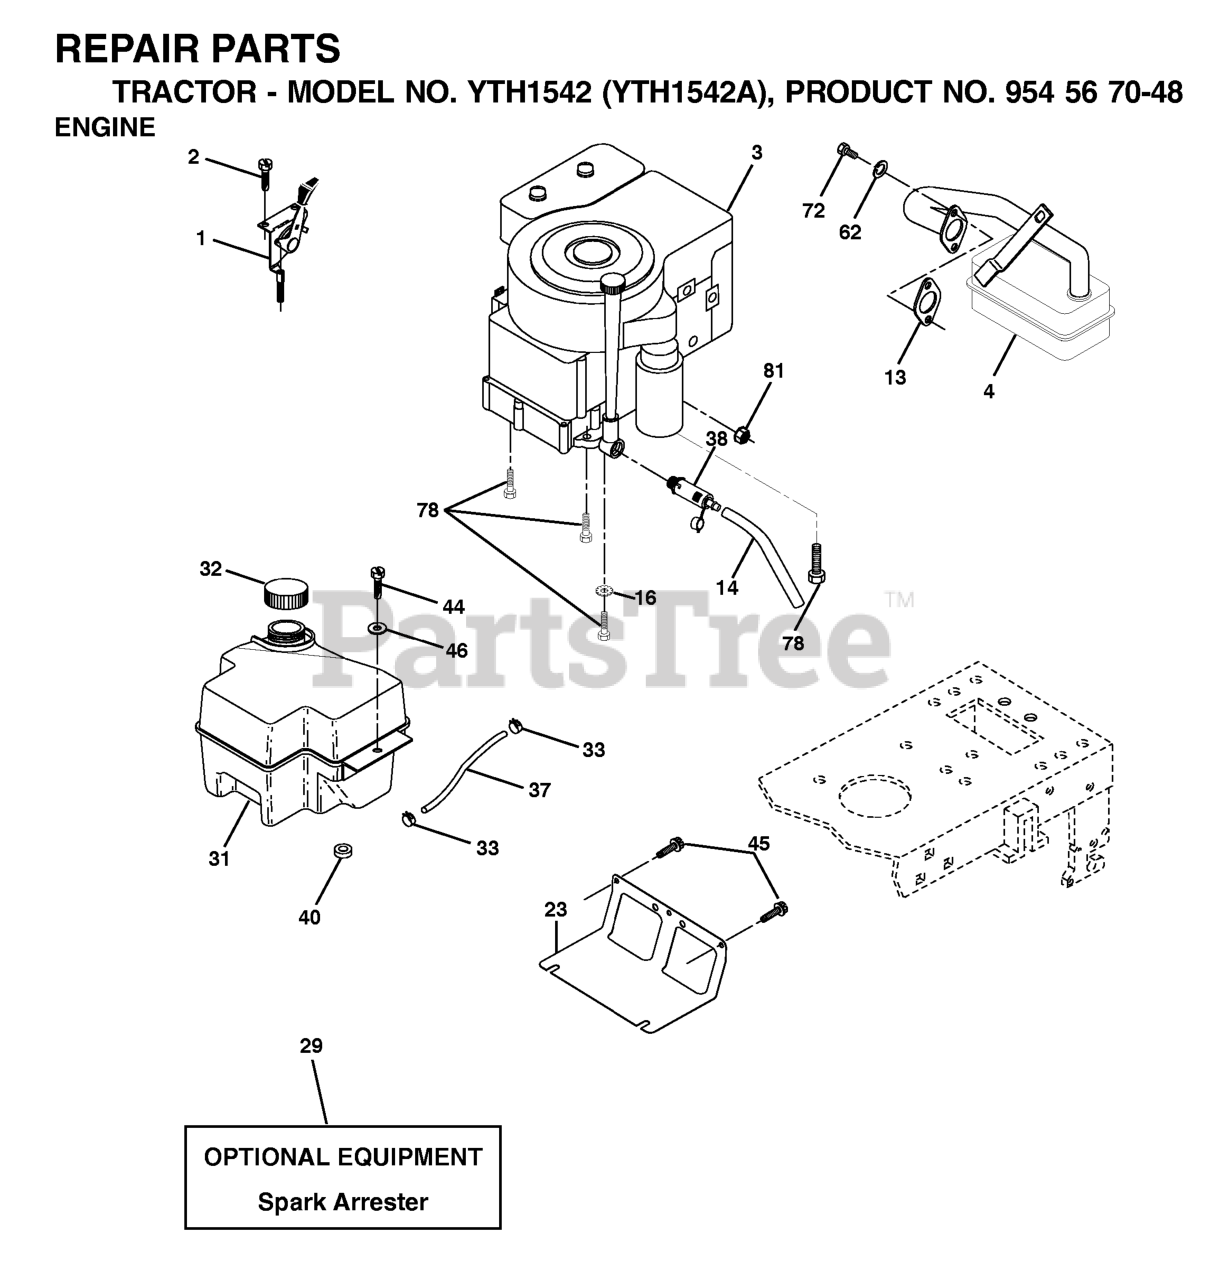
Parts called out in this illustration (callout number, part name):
1	CONTROL.THROTTLE/CHOKE.BLACK
2	SCREW LT
4	MUFFLER.LT.BRIGGS.14HP.IC/OHV
13	REPL BY 532 27 22-93
14	TUBE, DRAIN OIL ASM.
16	LOCKWASHER
23	SHIELD.BROWNING.DBR.GUARD
29	KIT.SPARK ARRESTOR 794945 B&S
31	TANK, 2GAL
32	FUEL CAP
33	HOSE CLAMP
37	LINE.FUEL.20
38	PLUG, OIL DRAIN EASY
40	BUSHING.SNAP.NYL.BLK.
44	SCREW HEXWSHR 1/4-20X3/4
45	SCREW, 3/8-16X3/4
62	WASHER.LOCK.HVY.HLCL.SPR.5/16
72	SCREW
78	SCREW.3/8-16
81	NUT
